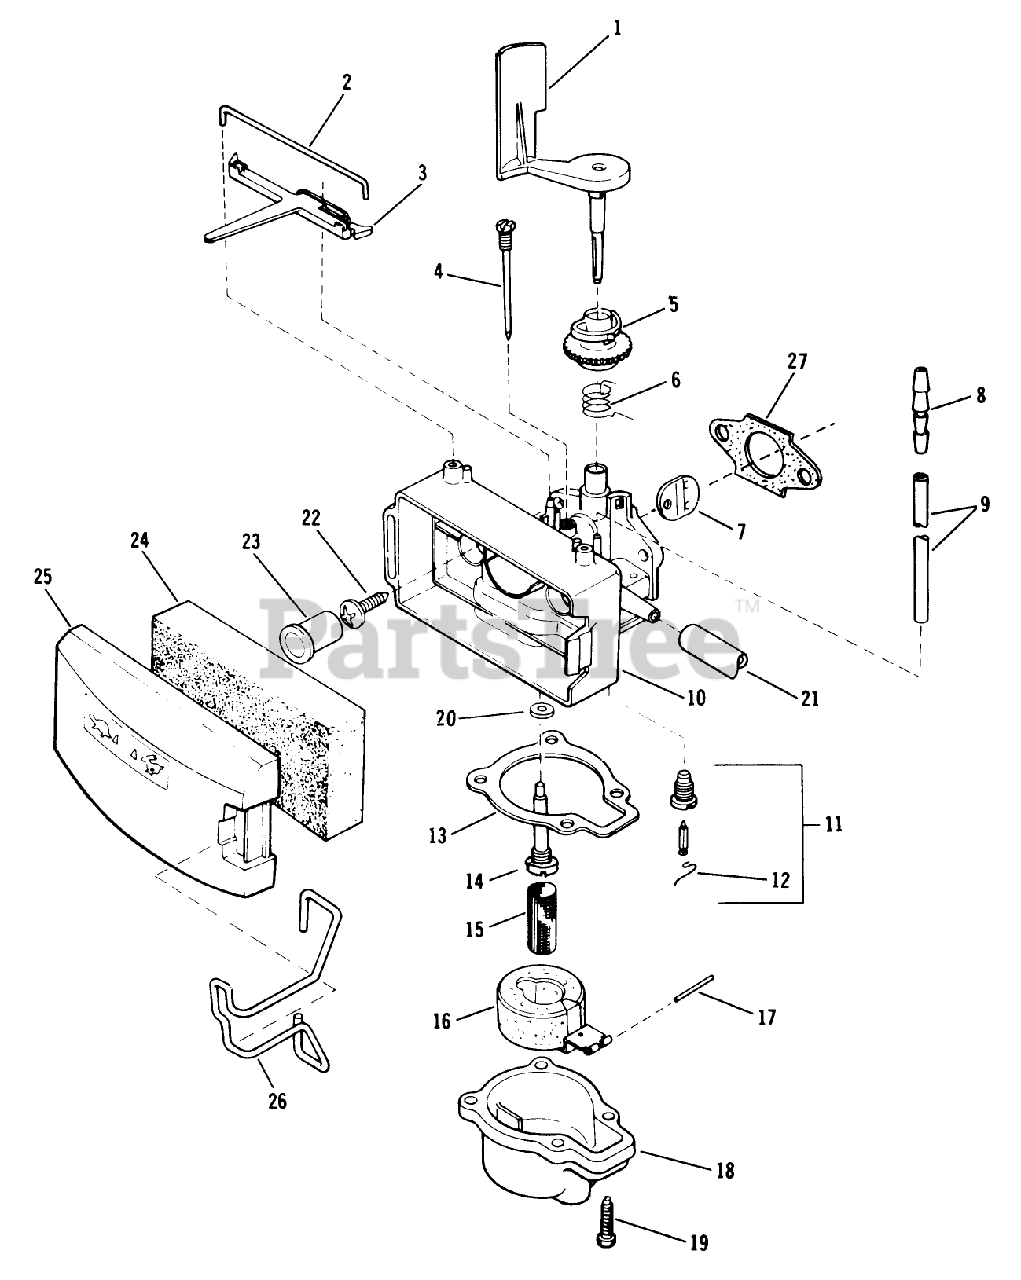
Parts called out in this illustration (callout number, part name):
2	RETAINER
3	LEVER S
4	NEEDLE ADJ. AY S
5	COLLAR-ADJUST, AIRVANE
6	SPRING,THROTTLE S
8	REDUCER-CONNECTOR
9	TUBING-PRIMER S
10	CARB BODY S
14	NOZZLE SER KIT S
15	FILTER-FUEL VS
19	SCREW-HH
26	RETAINER-COVER, FILTER
27	GASKET CARB S
